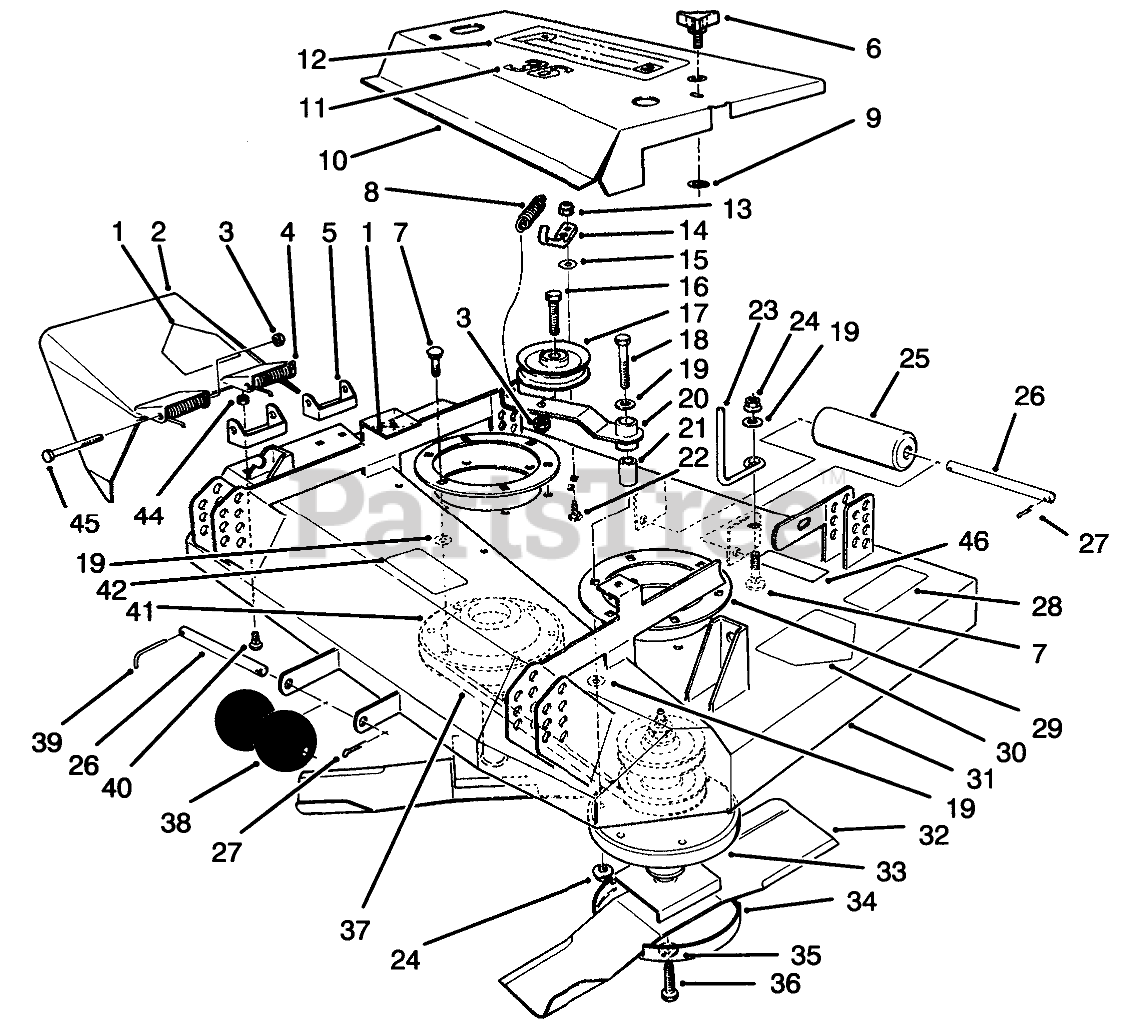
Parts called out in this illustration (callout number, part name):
1	DECAL-DANGER
2	Deflector-Grass (Incl. Ref.#1)
3	NUT-HEX
4	SPRING
5	Bracket-Pivot
7	SCREW-CARR
8	SPRING-EXTENSION
9	RING-RETAINING
10	Cover ASM
11	Decal-36 Inch
12	DECAL-PROLINE
13	NUT-LOCK, NI
14	ROD - SPRING
15	WASHER-FLAT
16	SCREW-HH
17	PULLEY-IDLER
18	SCREW-HH
19	WASHER-FLAT
20	Wa-Arm
21	SLEEVE-PIVOT, IDLER
22	SCREW-CARR
23	ROD-BELT
24	NUT-HF
25	ROLLER-DECK
26	SHAFT-ROLLER
27	PIN-COTTER
28	DECAL-TORQUE
29	SUPPORT-DECK, RING
30	DECAL-DANGER
31	Deck Assembly (Incl. Ref.#28,30,42 & 46)
32	BLADE-SAIL, EXTRA HIGH
33	HOUSING - SPINDLE ASM
34	CUP-SCALP, ANTI
35	WASHER-LOCK
36	SCREW-BLADE
37	V-BELT-DRIVE, DECK
38	ROLLER
39	PIN-SPECIAL
40	SCREW-CARR
41	SPINDLE ASM
42	DECAL-DANGER, THROWN OBJECT
44	NUT-LOCK, CONE
45	SCREW-HH
46	DECAL-DANGER
